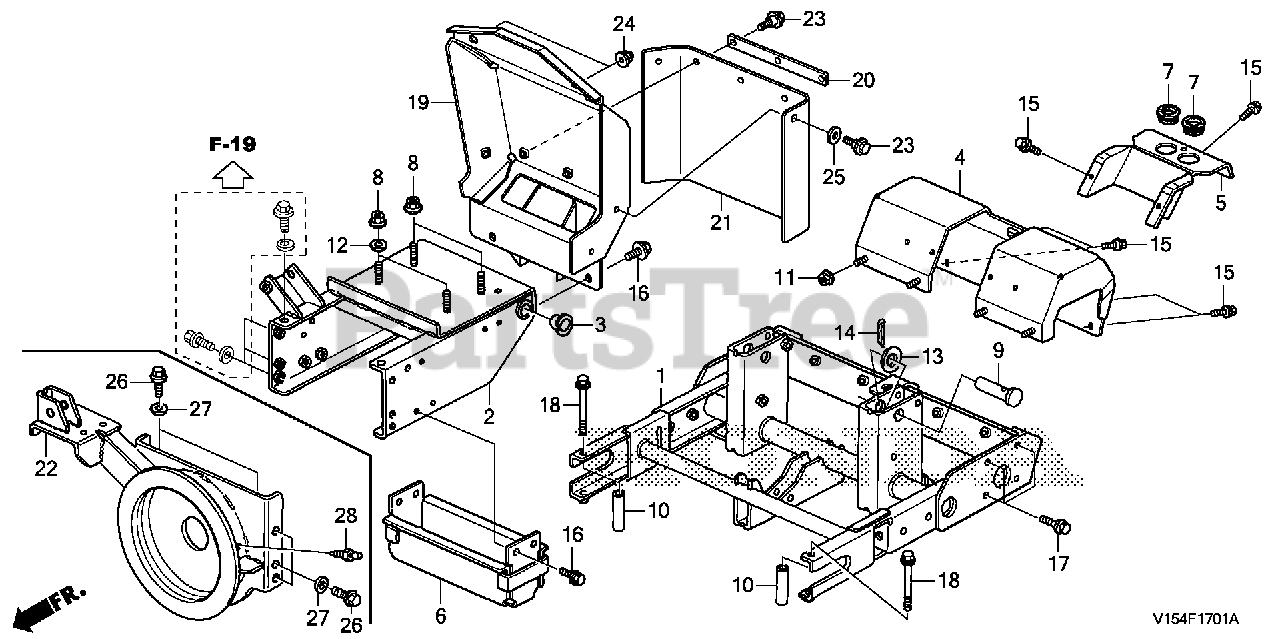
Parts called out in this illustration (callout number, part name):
1	FRAME, CRAWLER
2	FRAME, MAIN
3	BUSH, FRAME
4	COVER, MOTOR
5	COVER, MOTOR (UPPER)
6	COVER, BELT
7	GROMMET, TURN SIGNAL (NOT AVAILABLE)
8	NUT, FLANGE (10MM)
9	PIN, FRAME
10	COLLAR, FRAME CRAWLER
11	NUT, FLANGE (6MM)
12	WASHER, PLAIN (10MM)
13	WASHER, PLAIN (20MM)
14	PIN, SPLIT (3.0X35)
15	BOLT, FLANGE (6X12)
16	BOLT, FLANGE (8X16)
17	BOLT, FLANGE (8X20)
18	BOLT, FLANGE (8X85)
19	GUARD, FAN COVER
20	PLATE, ENGINE GUARD SEAL
21	SEAL, ENGINE GUARD
22	STAY, HOUSING *NH1* (BLACK)
23	BOLT, SPLASH GUARD
25	WASHER, PLAIN (10MM)
26	BOLT, FLANGE (10X20)
27	WASHER, PLAIN (10MM)
28	NIPPLE, GREASE (A.T6) (M6X1.0)
